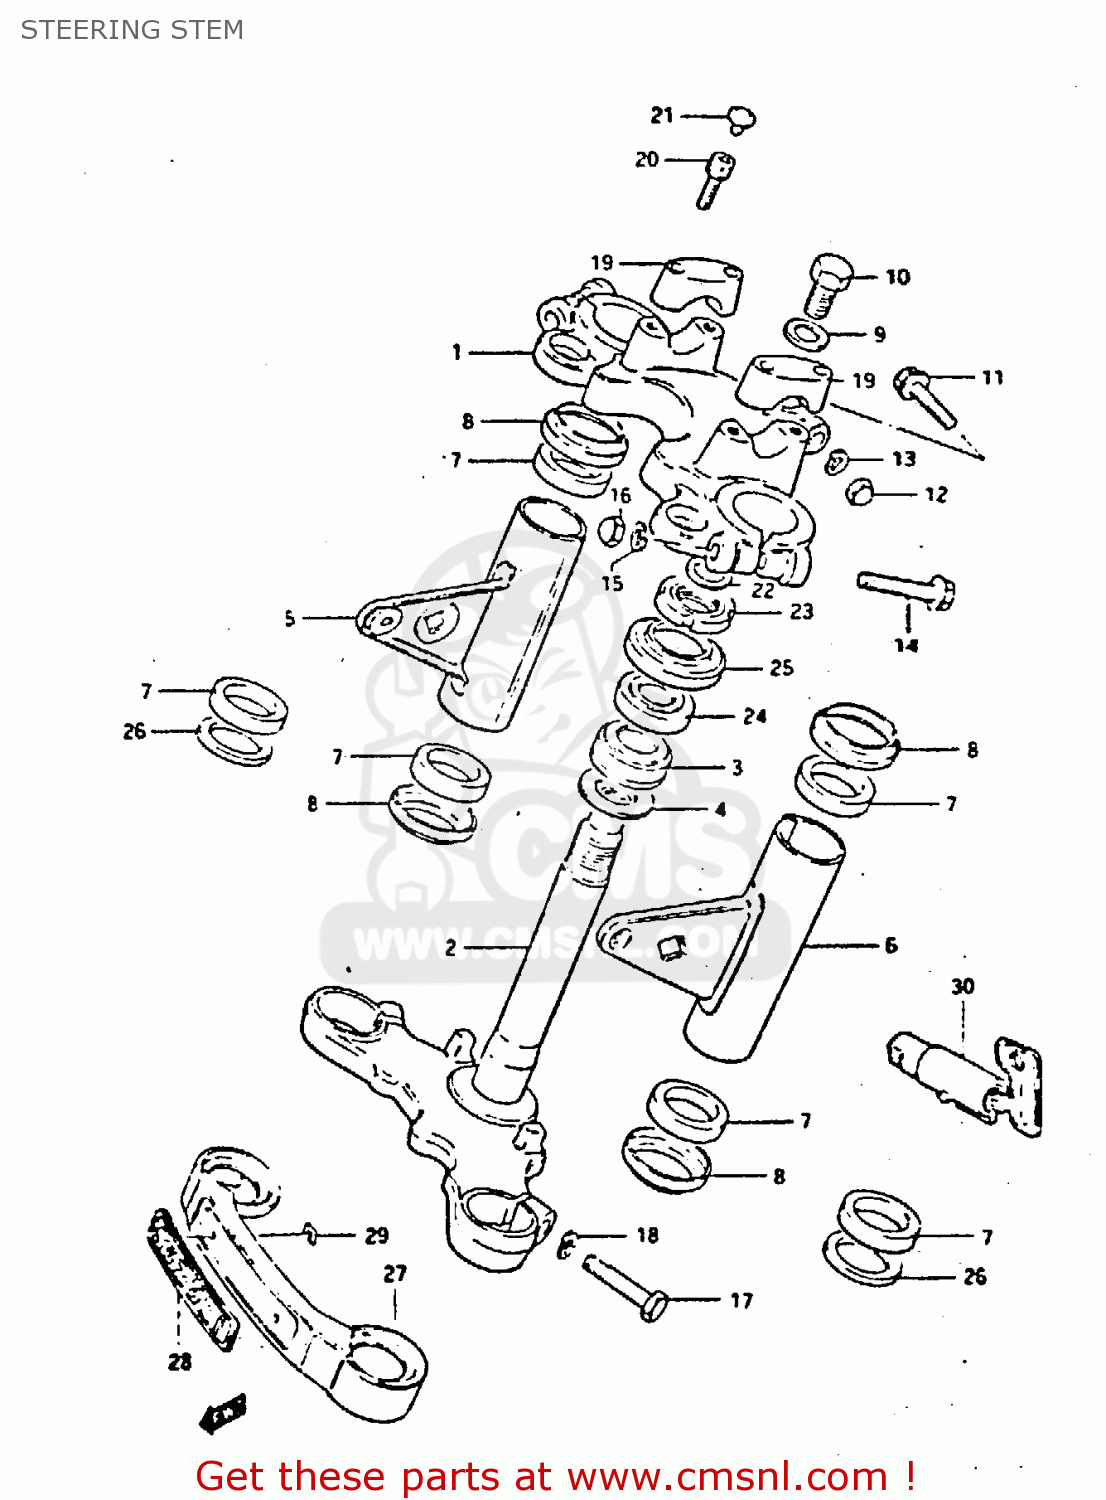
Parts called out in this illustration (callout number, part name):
1	HEAD,STEERING STEM
2	STEM,STEERING
3	BEARING
4	WASHER,THRUST
5	BRACKET,HEADLAMP,RIGHT
6	BRACKET,HEADLAMP,LEFT
7	CUSHION,HEADLAMP BRACKET
8	CAP,HEADLAMP BRACKET
9	WASHER (12.5X27X1.6)
10	BOLT(12X20)
11	BOLT, UPPER
12	NUT,M8X1.25X12
13	WASHER,LOCK,8.
14	BOLT
15	LOCK WASHER
16	NUT
17	BOLT
18	WASHER,LOCK
19	HOLDER,HANDLEBAR(BLACK)
20	BOLT, REAR (8X30)
21	CAP(OD:14.5)
22	WASHER(18.5X24X1)
23	NUT,STEERING STEM
24	TAPER,ROLLER BEARING
25	DUST SEAL,STEERING UPR
26	SEAT,HEADLAMP BRACKET LWR
27	COVER,FRONT FORK
28	EMBLEM,FR FORK COVER
29	NUT
30	LOCK ASSEMBLY,STEERING (NEI
